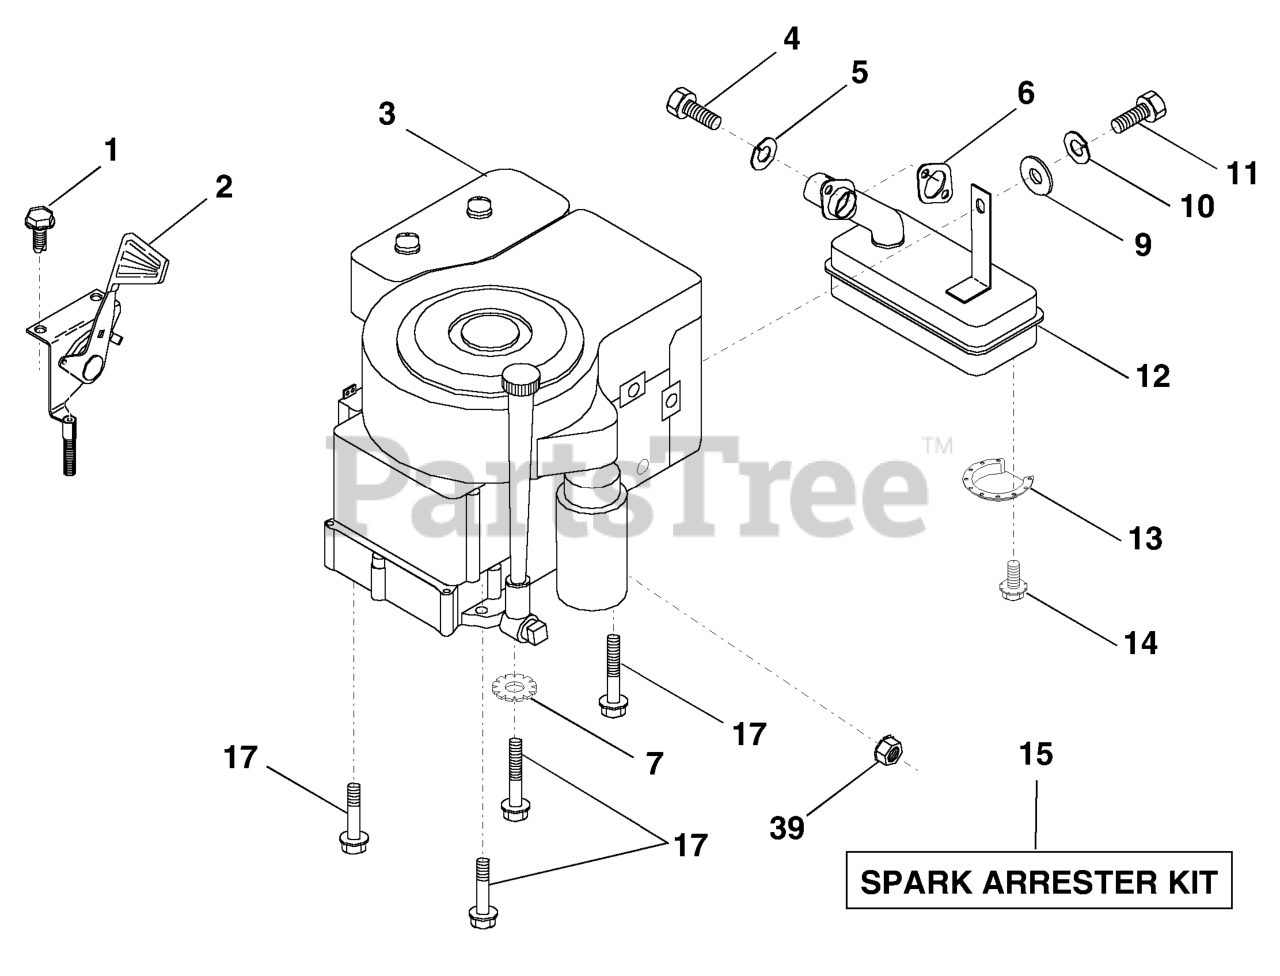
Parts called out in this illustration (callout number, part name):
1	SCREW LT
2	CONTROL.TH/CH.RH.BLK.FLG.26
4	SCREW
5	WASHER.LOCK.HVY.HLCL.SPR.5/16
6	REPL BY 532 27 22-93
7	LOCKWASHER
9	WASHER
10	LOCKWASHER
11	Bolt, Hex Fin.
12	MUFFLER.SINGLE.B&S.12HP
13	DEFL MUFFLER LTV
14	SCREW
15	KIT.SPARK ARRESTOR 794945 B&S
17	SCREW LT
39	NUT FLANGE 1/4-20 STARTER NUT
